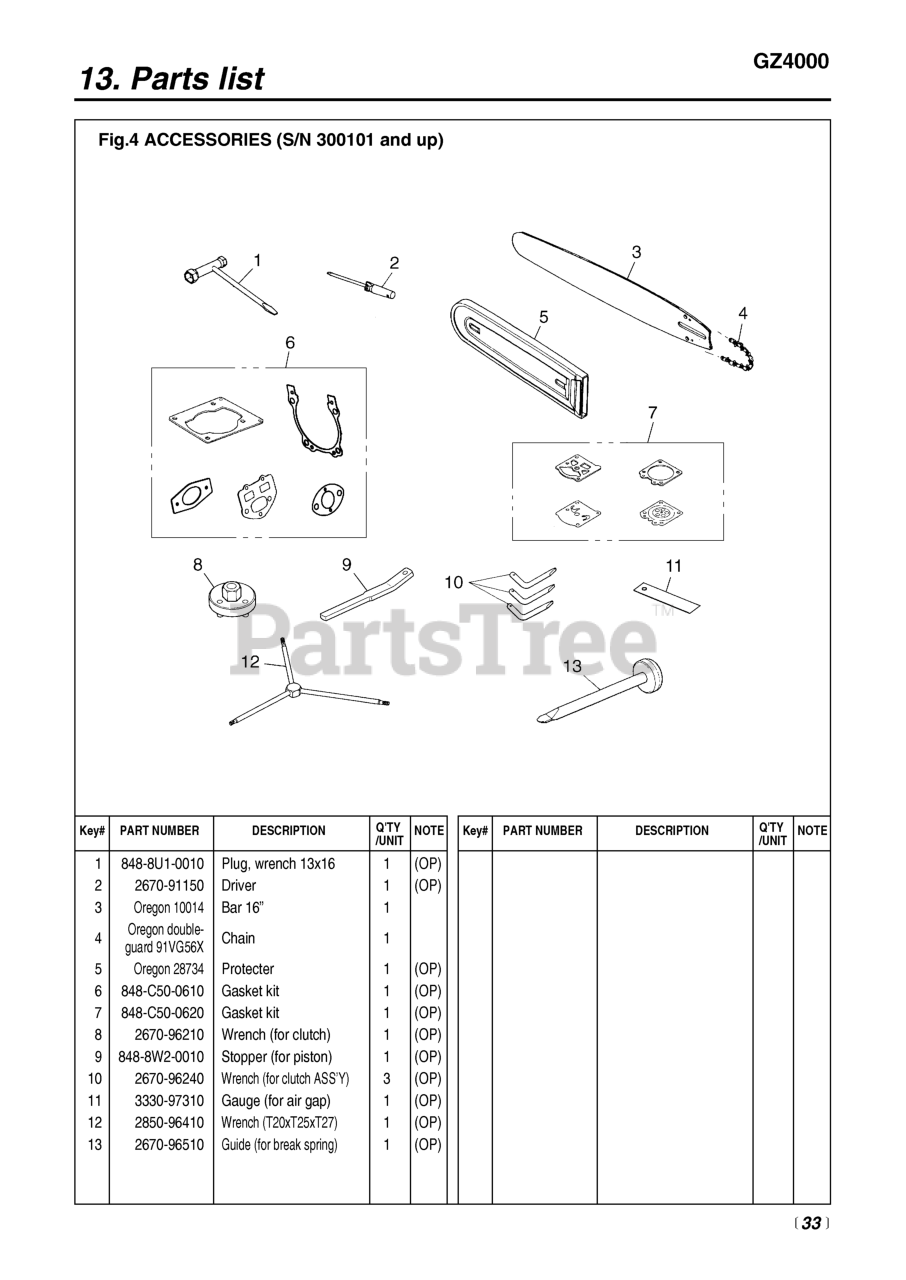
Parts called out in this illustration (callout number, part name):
1	WRENCH
2	SCREWDRIVER
3	BAR 16
5	PROTECTOR (OREGON 28734)
6	GASKET KIT (ENG)
7	GND-27- G-KIT
8	WRENCH (TOOL)
9	STOPPER
10	WRENCH (TOOL)
11	GAUGE (TOOL)
12	WRENCH (RPLS. 2670-96410)
13	GUIDE (TOOL)
